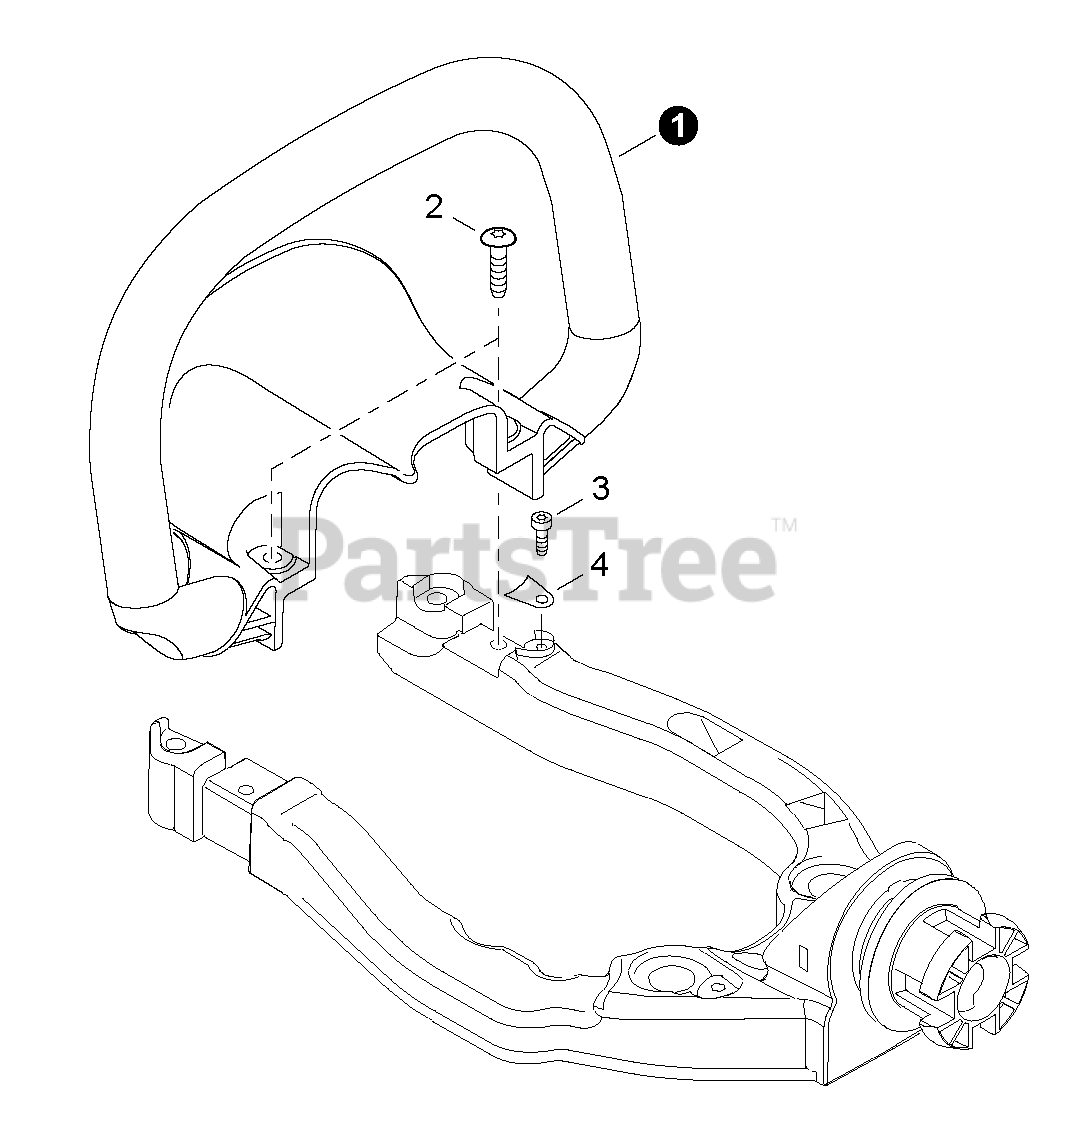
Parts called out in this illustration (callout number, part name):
1	HANDLE, FRONT
2	BOLT, TORX 6
3	BOLT, TORX 4×12
4	PLATE, EYE
